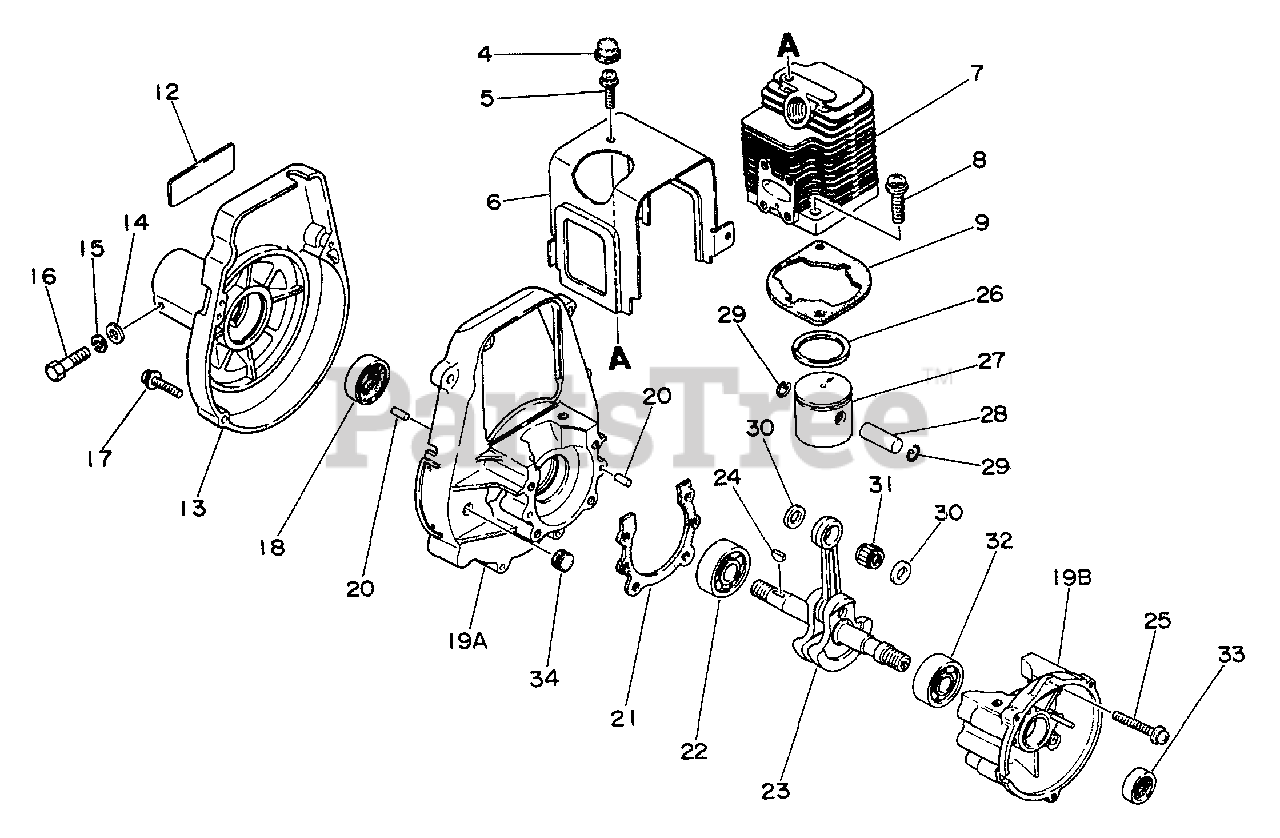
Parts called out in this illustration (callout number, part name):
4	SCREW - SOCKET HEAD CAP
5	SCREW 5×10
6	COVER, CYLINDER
7	CYLINDER
8	SCREW 6×20
9	GASKET, CYLINDER
12	LABEL - MODEL
13	COVER, FAN
14	WASHER, FLAT 5.5×10×0.8
15	WASHER, SPRING 5
16	BOLT 5×25
17	SCREW 4×20
18	SEAL, OIL 12
19	CRANKCASE KIT
19A	CRANKCASE KIT
19B	CRANKCASE KIT
20	PIN, LOCATING 4
21	GASKET, CRANKCASE
22	BEARING, BALL - 6201 C3
23	CRANKSHAFT ASSY
25	SCREW 5×30
26	RING, PISTON
27	PISTON
28	PIN, PISTON
29	RING, SNAP
30	WASHER, THRUST
31	BEARING, NEEDLE
32	BEARING, BALL 6200
33	SEAL, OIL
34	PLUG
